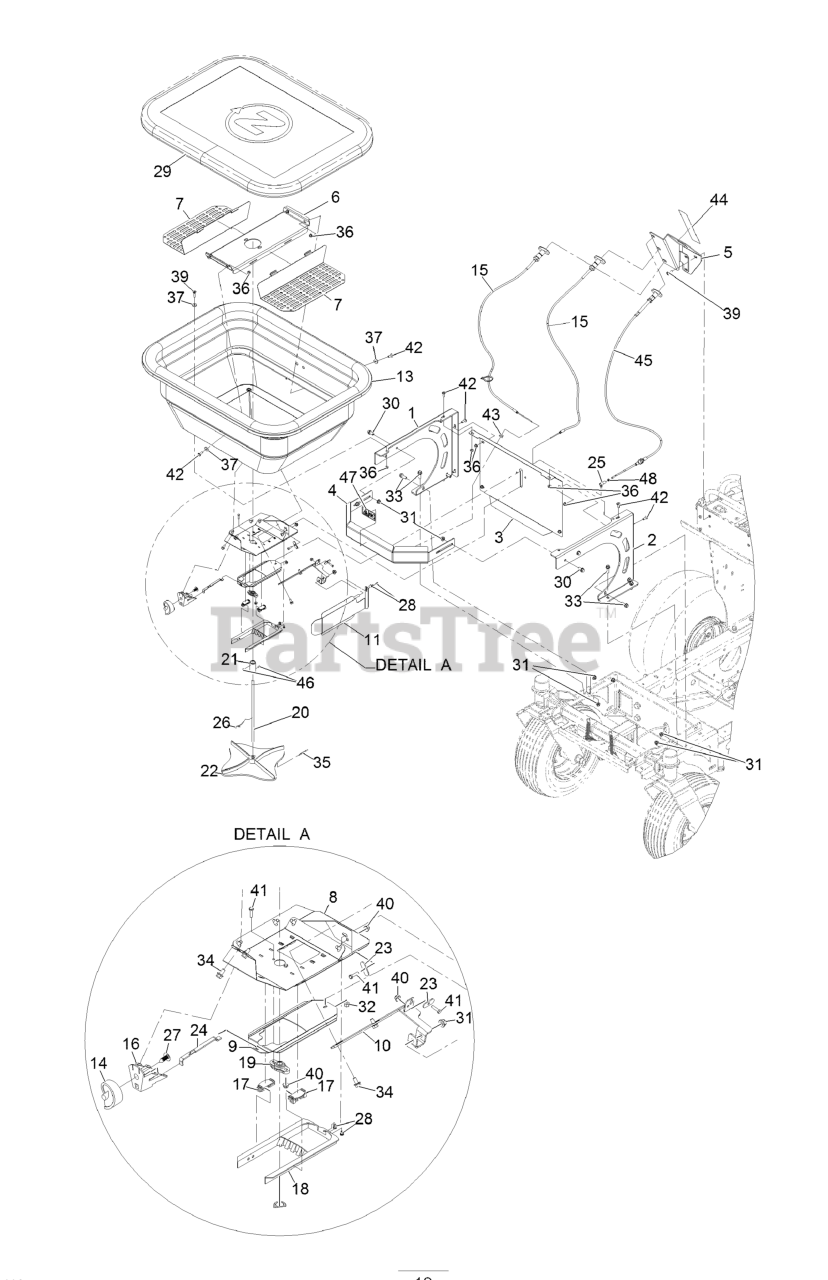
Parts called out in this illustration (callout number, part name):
1	Side-Hopper, Rt
2	Side-Hopper, Lt
3	Backshield-Hopper
4	BUMPER-FRONT, HOPPER
5	MOUNT-SPEEDOMETER
6	PAN-HOPPER, 220
7	SCREEN-HOPPER, 220
8	PLATE-BASE, HOPPER
9	Slide-Door, Hopper
10	Mount-Deflector, Side
11	Deflector-Side, Spreader
13	HOPPER-220LB
14	DIAL
15	CABLE-PUSH/PULL
16	MOUNT-DIAL
17	GUIDE-RATE, GATE
18	DIFFUSER
19	BEARING-FLANGE
20	SHAFT-HOPPER, 220
21	COUPLER-SS
22	SPINNER-SPREADER
23	RETAINER, CABLE
24	LINKAGE-GATE, RATE
25	BALL JOINT-SS
26	WIRE-AGITATOR
27	CLIP
28	RETAINER-CABLE, WIRE
29	COVER-HOPPER, LARGE
30	SCREW-HHF
31	Nut-Hex Flange
32	Nut,NYL Lock,#10-32,ST/ST 18-8
33	SCREW-HHF
34	SCREW-HHF
35	PIN-COTTER
36	Nut-Hex Flange
39	Screw-Hsbhf
40	Nut-Hex Flange
41	SCREW-HH
42	Screw-Hsbhf
43	Grommet-Rubber
44	Decal-Hopper Control
45	CABLE-PUSH/PULL
46	Screw-SQH
47	Decal-Dismemberment Hazard
48	Nut,Hex Jam Mch Scr,10-32,Sst
